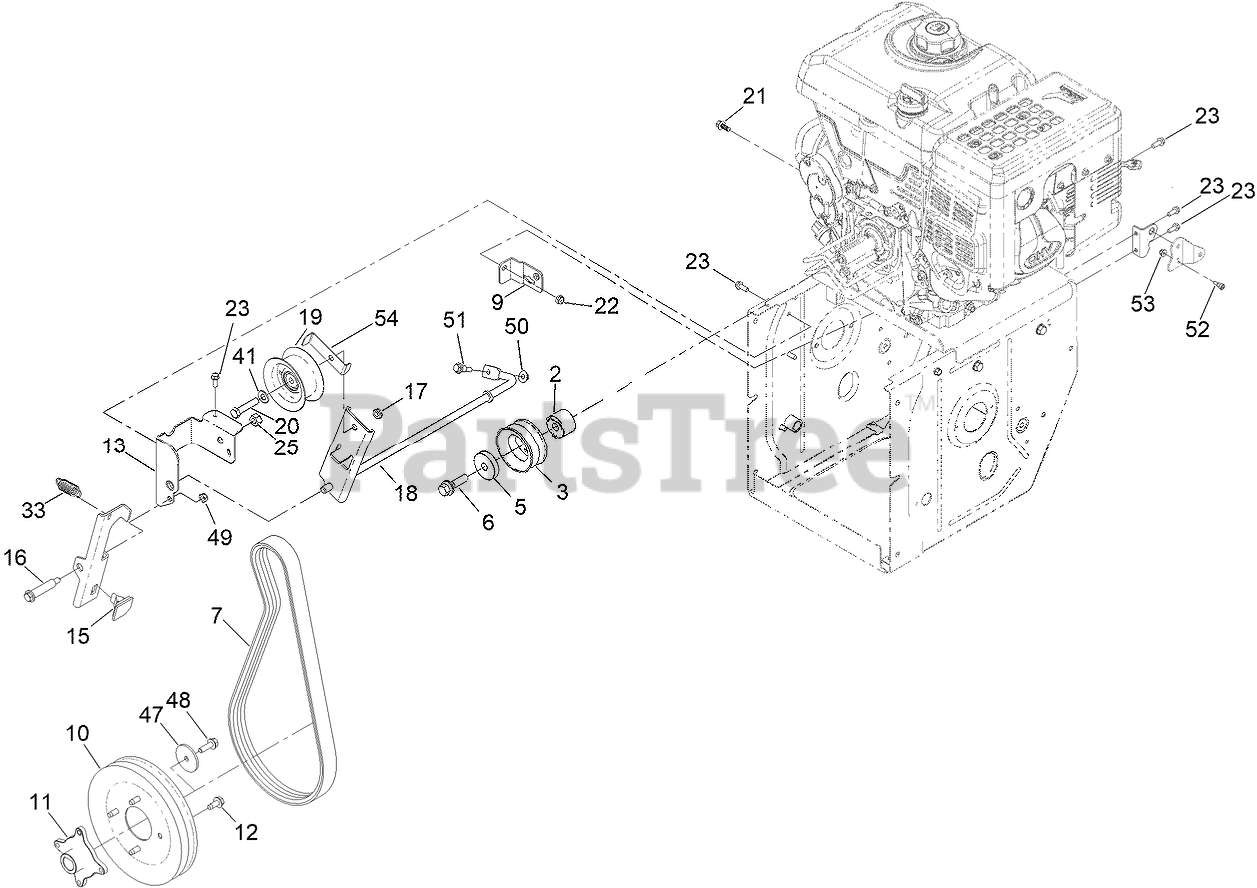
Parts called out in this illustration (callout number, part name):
2	PULLEY-SPACER
3	PULLEY-IMPELLER, DOUBLE SHEAVE
5	SUPPORT-PULLEY
6	BOLT-BLADE
7	BELT-V
9	BRACKET-CLUTCH, IMPELLER
10	PULLEY-IMPELLER, DOUBLE SHEAVE
11	HUB-PULLEY
12	SCREW-HWHTF
13	BRACKET-BRAKE, CLUTCH
15	PAD-BRAKE
16	BOLT-SHOULDER
17	NUT-HEX
18	ARM-CLUTCH, IMPELLER
19	PULLEY, IDLER
20	SCREW-HH
21	SCREW-HHF
22	NUT-HF
23	SCREW-HWH
25	NUT-HEX
33	SPRING-EXTENSION
41	WASHER-FLAT
47	WASHER-PLAIN
48	SCREW-HHF
49	NUT-HEX
50	NUT-HF
51	BOLT-SHOULDER
52	SCREW-SHOULDER
53	NUT-HF
54	STOP-ARM
